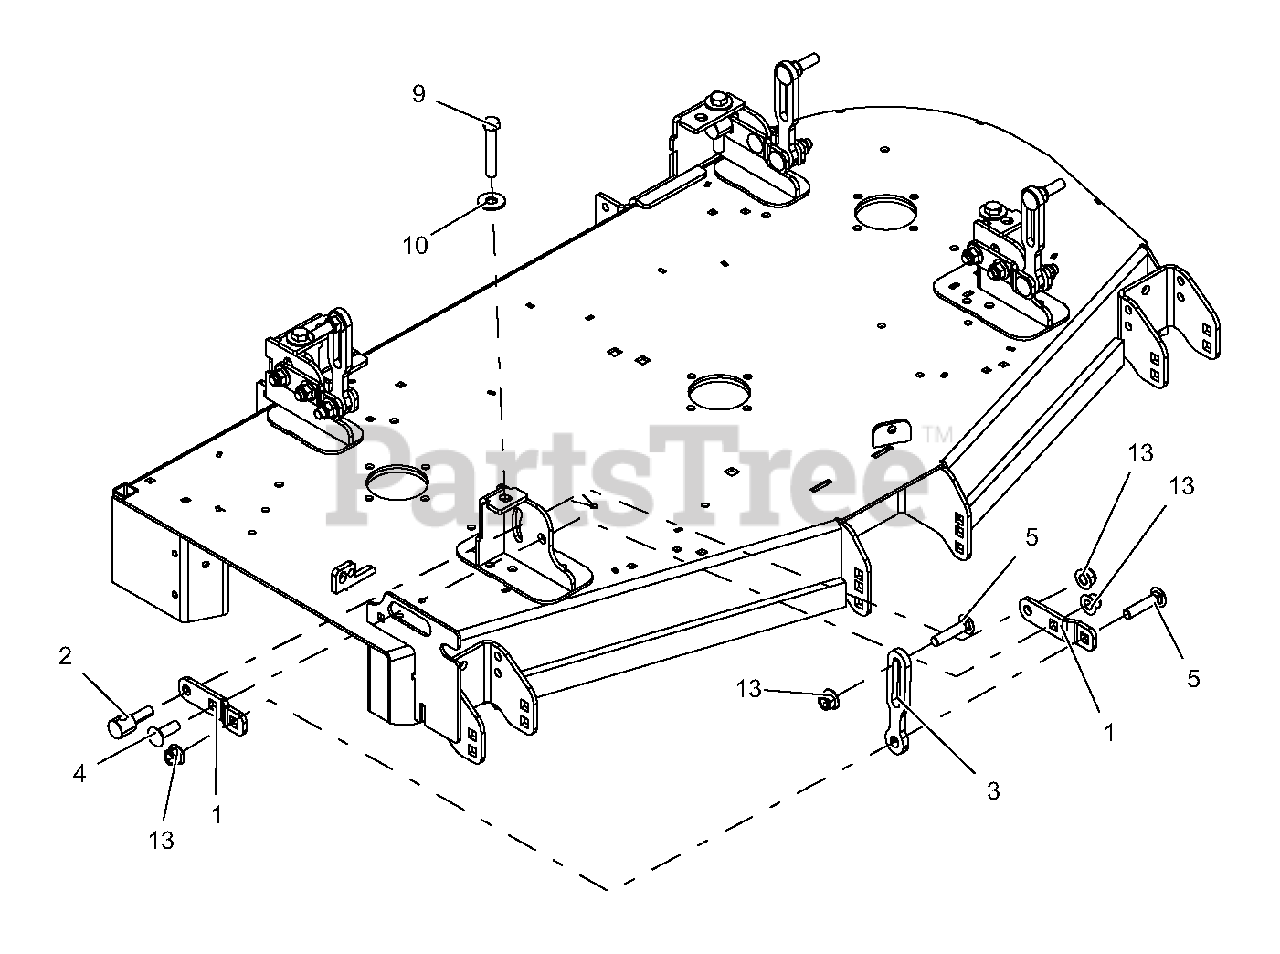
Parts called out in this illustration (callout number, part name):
1	BRKT, DECK LEVELING-BLACK
2	TRUNNION, .50-13
3	LINK, DECK LIFT
4	@BLT-RDHDSQNK .50-13X1.50 G5 YWZC
5	BLT-RDHDSQNK .50-13X2.25 G5 Y
9	BLT-HEX .50-13X3.00 GR5 FTH YZ
10	@WSHR-FL-STL.563X1.38X.109YWZC
13	NUT-LK-NYL-FLG .50-13 YWZC
